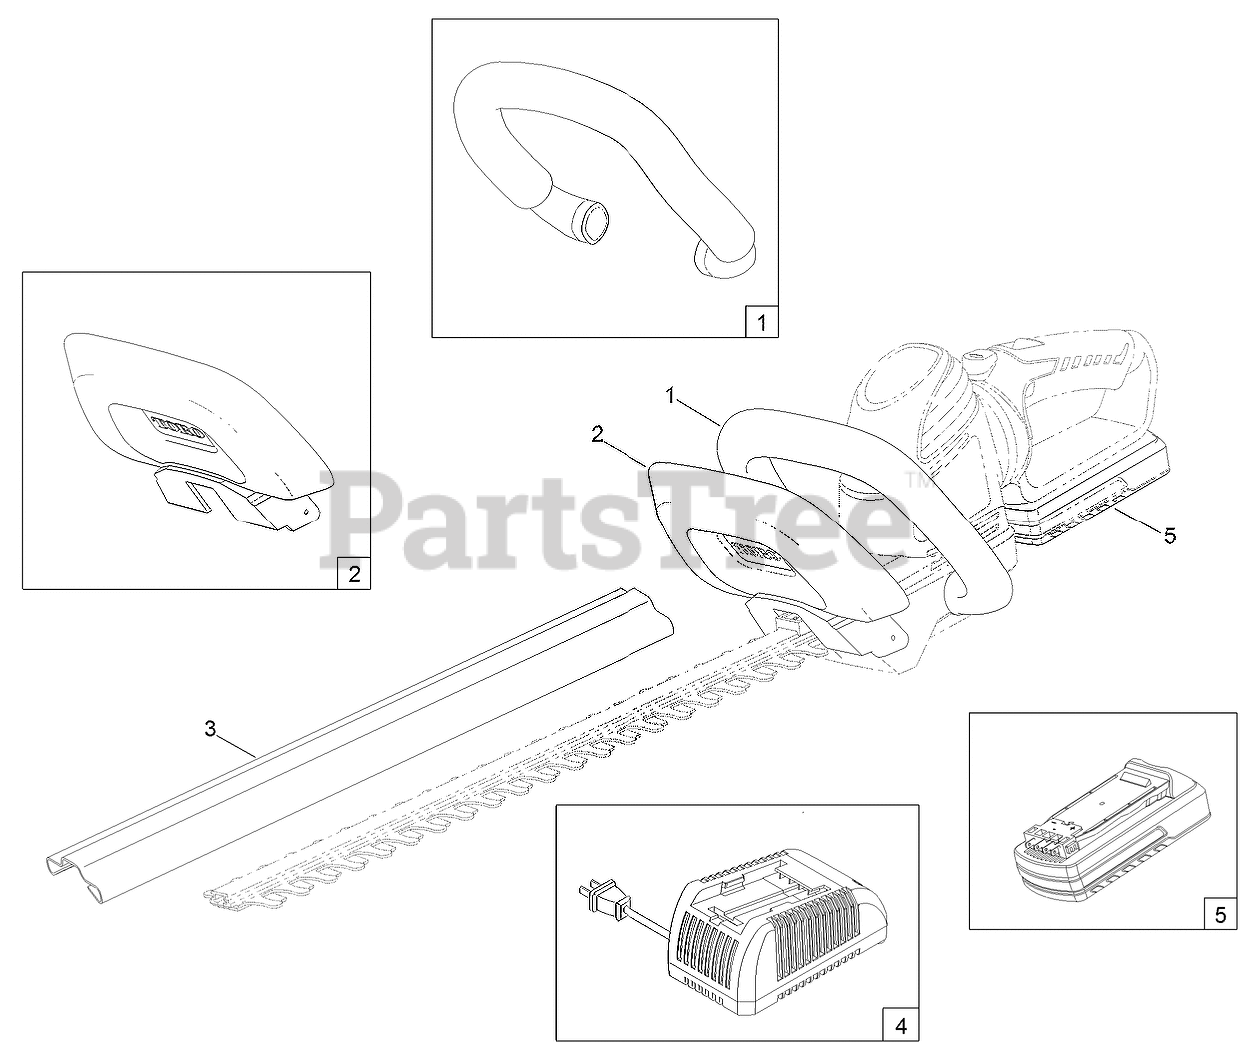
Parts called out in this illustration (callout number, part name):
1	HANDLE-ASSIST
2	GUARD ASM
3	SHEATH-BLADE
4	CHARGER-24V, LI-ION BATTERY
5	BATTERY-LI-ION, 24V, 2.0AH
